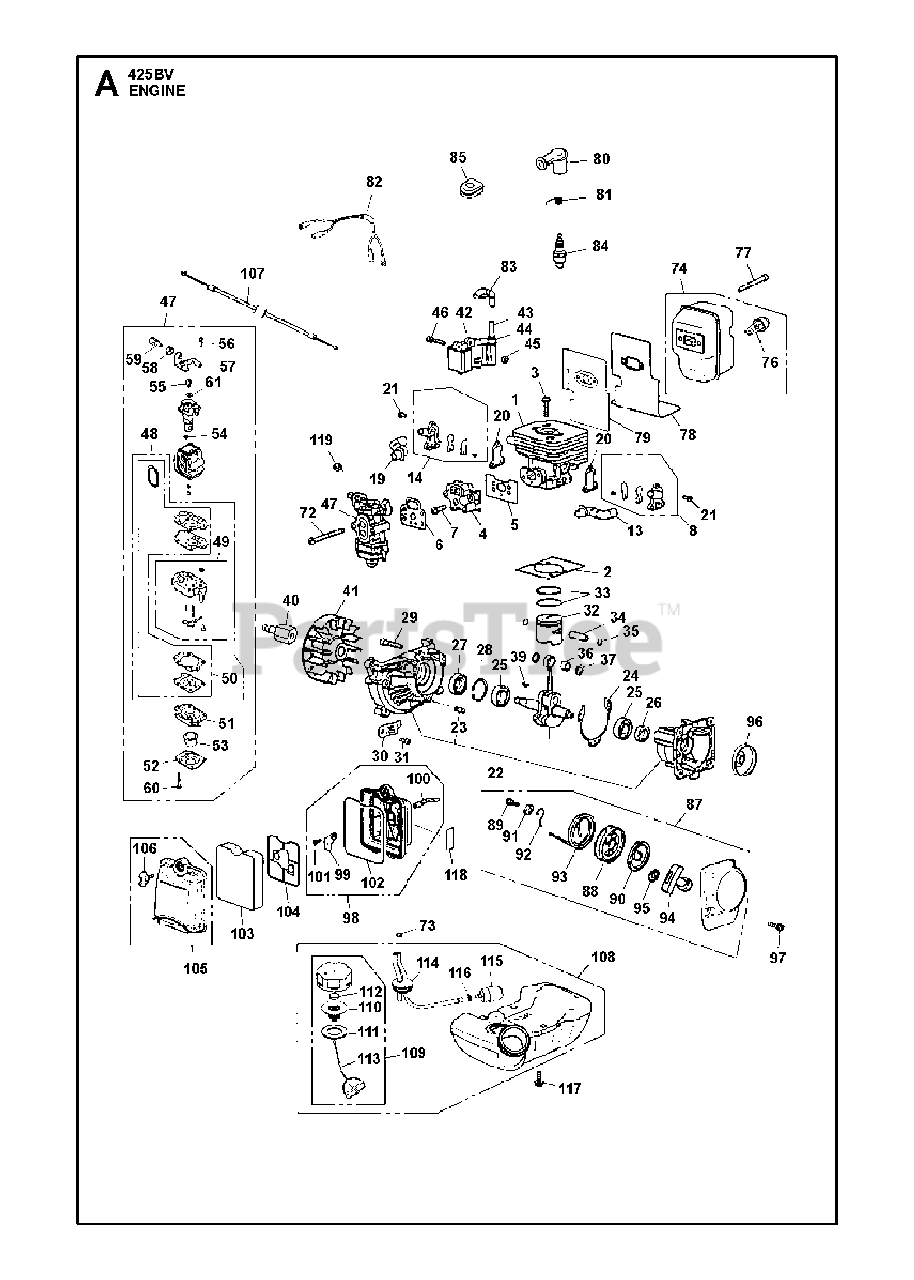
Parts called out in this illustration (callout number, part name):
2	GASKET, BASE
5	GASKET.INSU
7	BOLT
8	REEDVALVE(S)-A
13	PIPE AIR (S)
14	REEDVALVE(F)-A
19	PIPE AIR (F)
20	GASKET, VALVE
22	CRANKCASE-C
23	PIN
24	GASKET.CASE
25	BEARING
31	BOLT 08
34	PIN (RPLS T151341310)
36	BEARING (R550041410&114041330)
38	CRANKSHAFT COMP(RPLS481042000)
40	EXTENSION.
43	CORD (BLACK)
44	CAP
47	CARBURETOR-A
48	REBUILD KIT
49	CARBURETOR BODY
50	GASKET KIT
51	BODY
52	1OVER
53	PUMP
54	RING
55	SWIVEL
56	SCREW
57	BRACKET
58	NUT
60	SCREW
61	WASHER
76	ARRESTER
78	GASKET, MUFFLER
79	PLATE, MUFFLER
84	PLUG CMR7H
85	GROMMET
88	REEL
89	SCREW
90	SPRING, SPIRAL
91	COLLAR
92	SWING ARM
93	ROPE
94	KNOB
95	PLATE.STOPPER
99	PLATE.CHOKE
100	LEVER CHOKE
101	SCREW
102	PACKING
105	COVER ASSY
106	KNOB
109	CAP A
110	HOLDER-A
111	PACKING
112	FILTER
113	STOPPER
114	PIPE-C
115	FILTER
116	CLIP
118	LABEL, CHOKE
